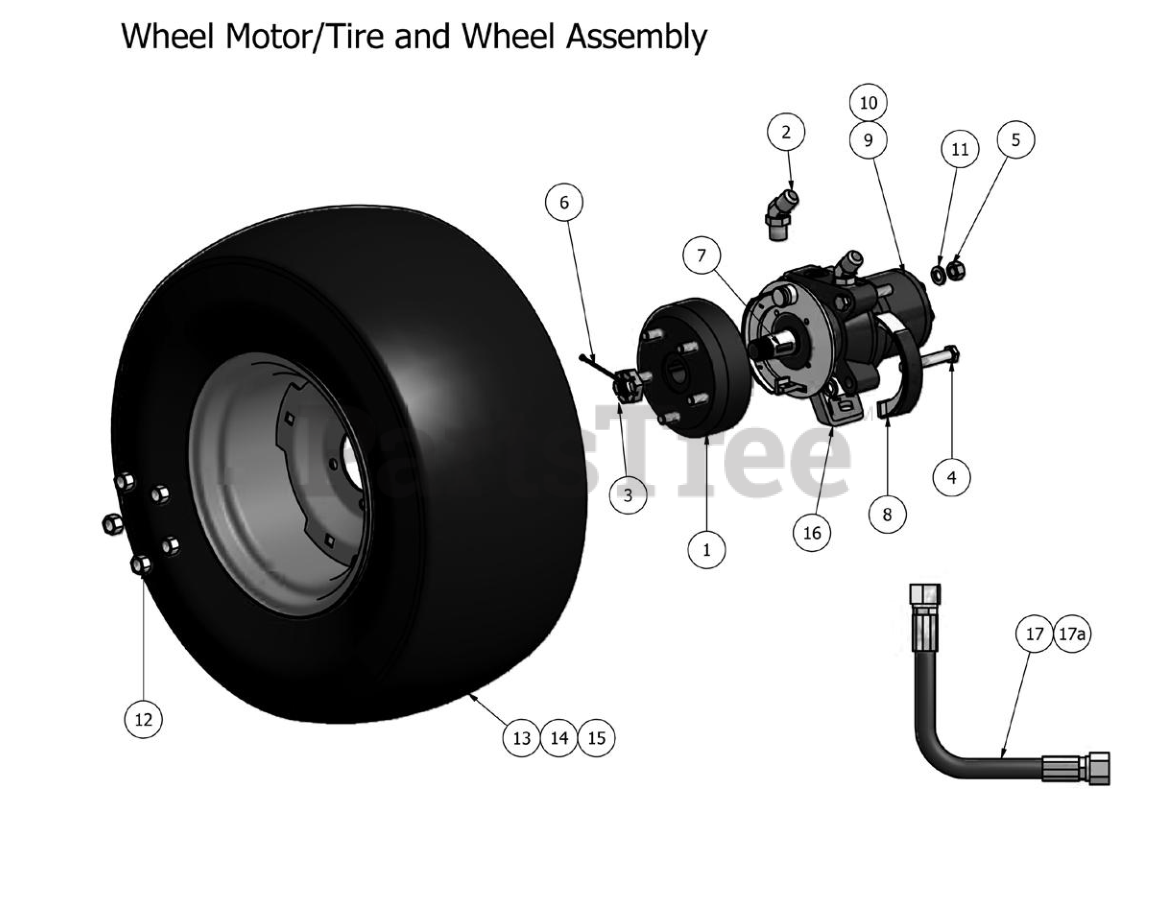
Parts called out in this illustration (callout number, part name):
1	Brake Drum
2	Hydraulic Fitting
3	Castle Nut
4	1/2" 13 x 3" GRS Hex Bolt Zinc
5	1/2" Hex Nut
6	1/8"x2 1/4" Cotter Pin
7	Woodruff Key
8	Brake Shoe
9	Wheel Motor and Drum Brake Combo-18E Right
10	Wheel Motor and Drum Brake Combo-18E Left
11	1/2" Lock Washer
14	26" x 12-12 Tire -60" & 72" Cut
15	26" Tire and Wheel Assembly
16	Brake Lever (wheel motor) Left
17	Hydraulic Hose 60" Deck
